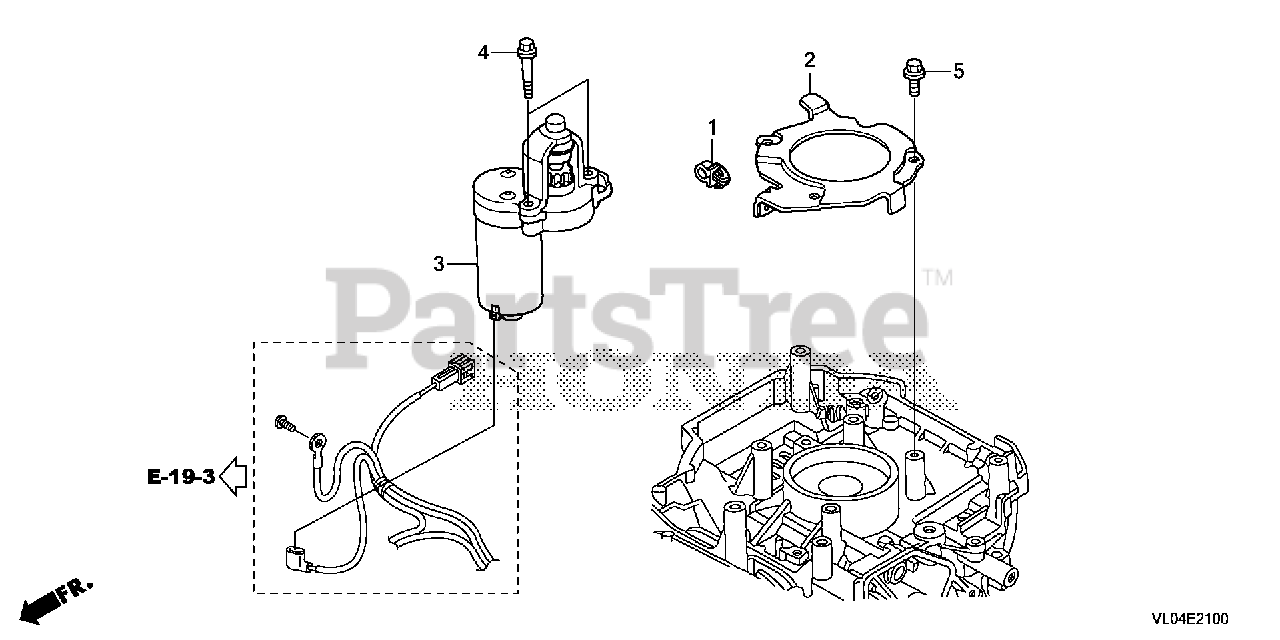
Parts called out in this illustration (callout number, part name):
1	HOLDER, WIRE
2	CLAMP, WIRE
3	STARTER MOTOR ASSY.
4	BOLT, SPECIAL (6MM)
5	BOLT, FLANGE (6X12) (CT200)
